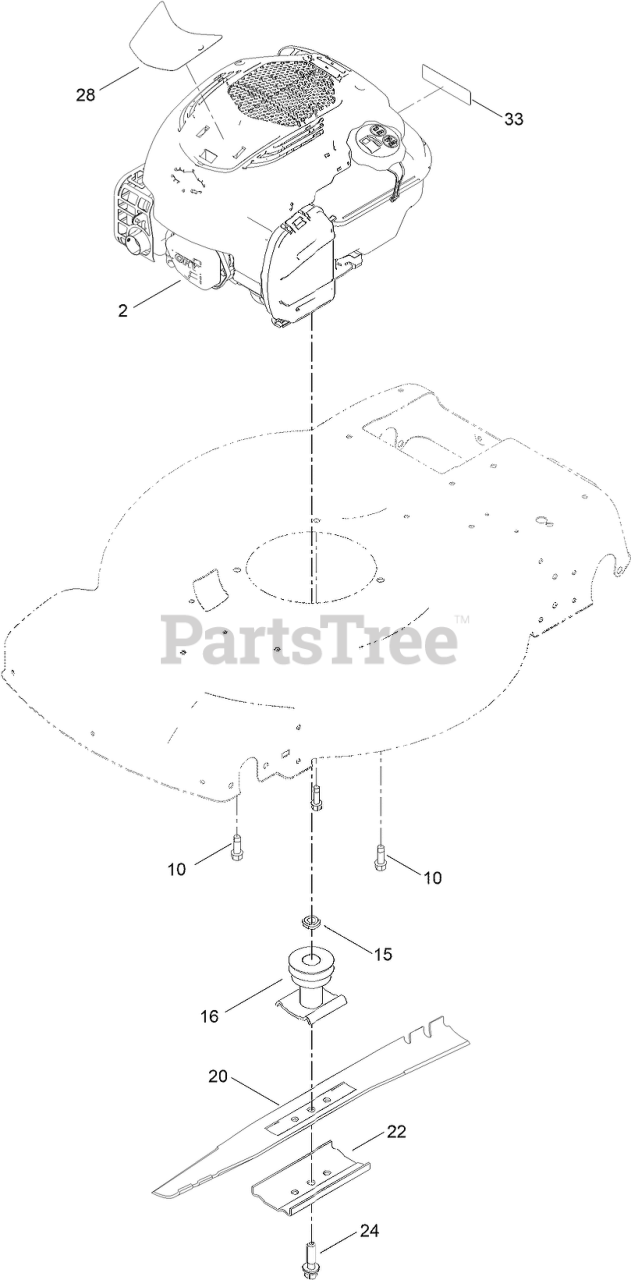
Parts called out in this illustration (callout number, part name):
10	SCREW-THD FORM, HWH
15	SPACER-DRIVER
16	DRIVER-BLADE
20	BLADE-22 INCH
22	SUPPORT-BLADE
24	BOLT-BLADE
28	DECAL - BRIGGS 725 EX
33	DECAL-ARRESTOR, SPARK
